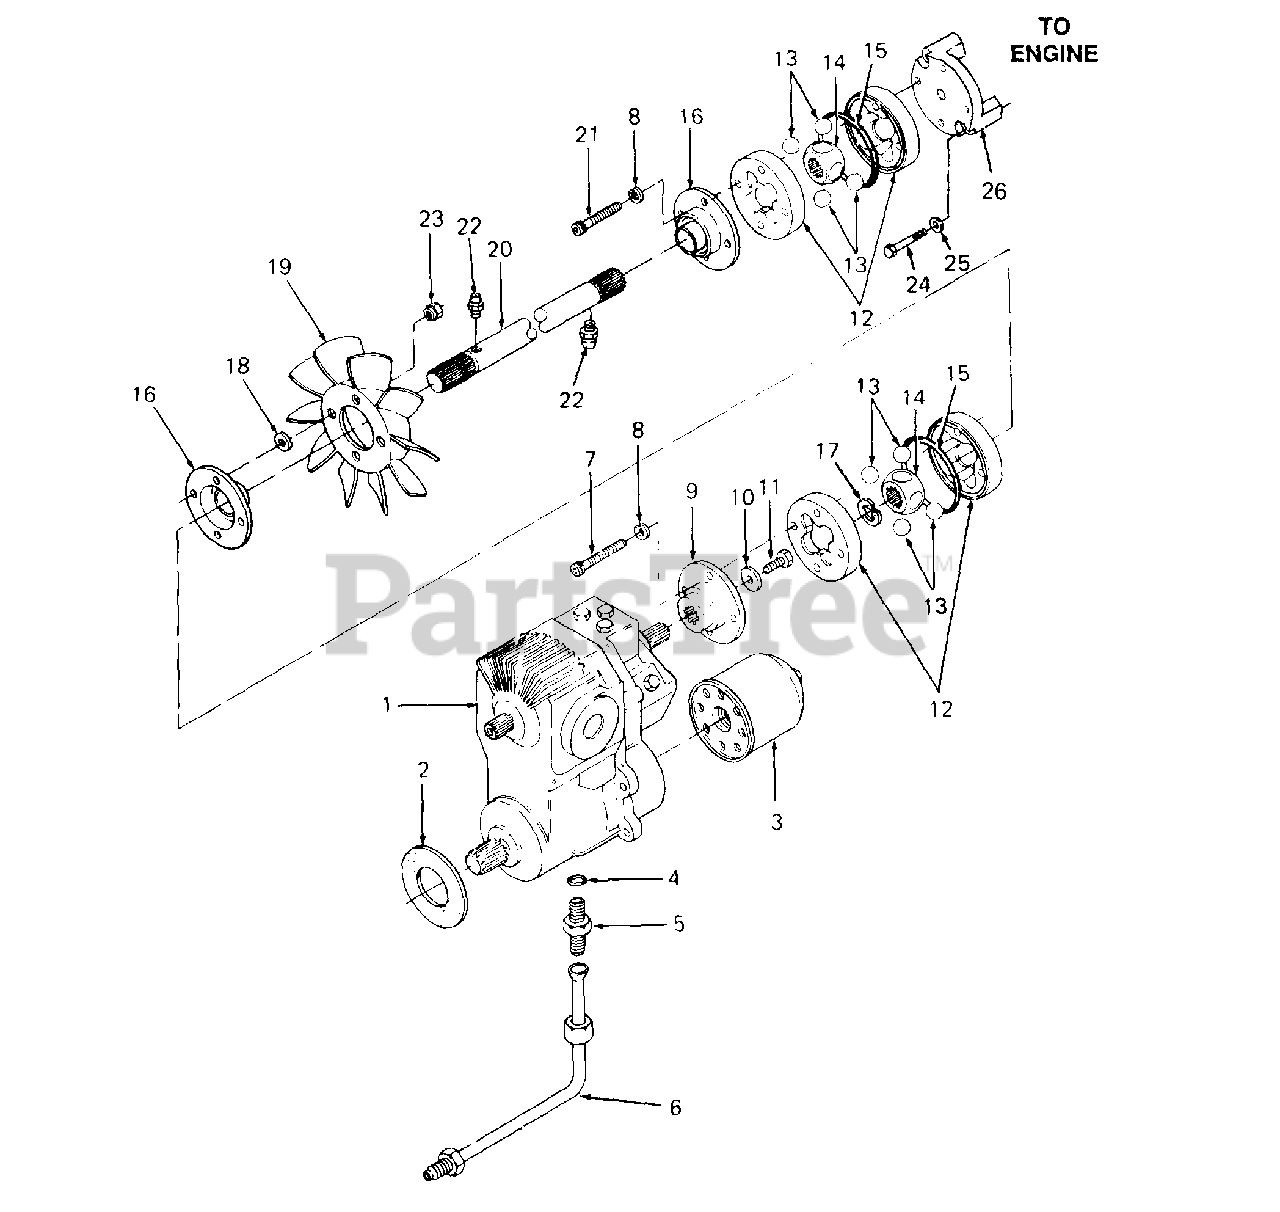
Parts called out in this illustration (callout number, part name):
1	Pump, Hydrostatic
2	Gasket, Front
3	Filter, Oil
4	O-Ring, 5/8 OD Tube
5	Connector, 37 Degree
6	Tube Assy
7	Screw, Socket Hd Cap, 1/4-20 X 2.0 Lg
8	Washer, Lock, 1/4
9	Adapter, Pump
10	Washer, Bell, .265 X .75 X .062 Thk
11	Bolt, Hex Patch, 1/4-20 X 1.0 Lg GR5
12	Coupling, Drive w/O-Ring Groove
13	Ball, Steel, 5/8 Dia Chrome
14	Hub, Drive
15	O-Ring, 2.489 X .070
16	Boot, Coupling
17	Ring, Snap
18	Washer, Flat, .25 X .62 X .052 Thk
19	Fan, 10 Blade Hydro
20	Shaft, Drive, 26.15 Lg
21	Screw, Socket Hd Cap, 1/4-20 X 1.75 Lg
22	Fitting, Grease
23	Nut, Fan 1/4-20
24	Bolt, Hex Patch, M8-1.25 X 50 MM
25	Washer, Flat, .312 X .750 X .119 Thk
26	Adapter, Drive Shaft
